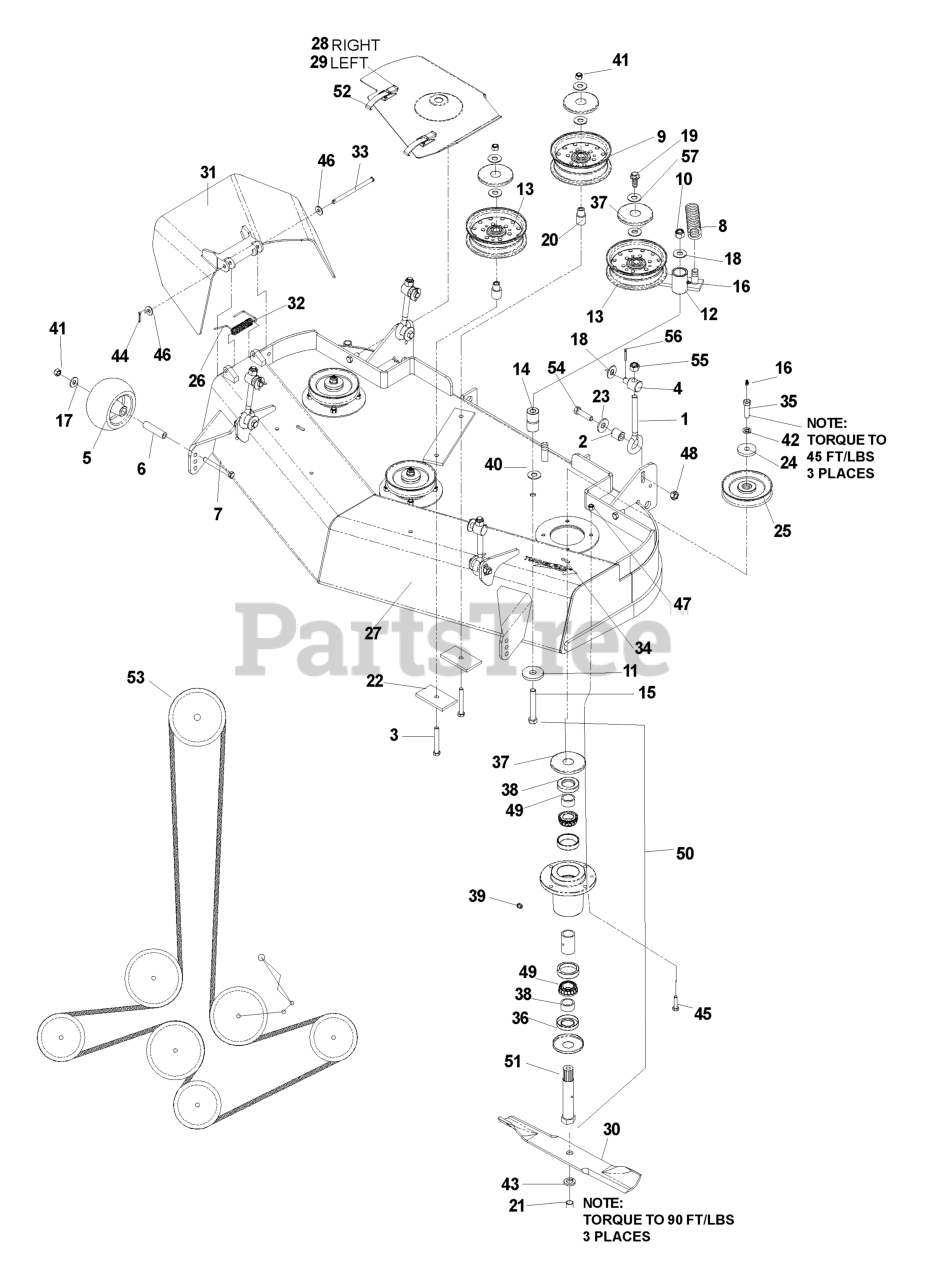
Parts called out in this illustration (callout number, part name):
3	HCS, 3/8-16 X 2 3/4, GR5
5	ROLLER, ANTI SCALP
7	HCS, 3/8-16 X 3 1/2, GR8
8	SPRING, EXTENSION
9	PULLEY, IDLER
10	NUT, 1/2-13, NYLOC
11	WASHER, .65
13	PULLEY, IDLER
14	BUSHING, PIVOT
15	HCS, 1/2-13 X 3 1/4, GR5
16	ZERK, STRAIGHT, 1/4-28
17	WASHER, 3/8
18	WASHER, 9/16
19	HCS, 3/8-16 X 1,GR5
20	BUSHING, IDLER
21	HCS, 5/8-18 X 1 1/4, GR5
22	PAD
23	SPRING WASHER, 1/2
24	WASHER, .469
25	PULLEY
26	CAP-SLEEVE
27	DECK W/DECALS
28	BELT SHIELD, RIGHT
29	BELT SHIELD, LEFT
30	BLADE, 14 5/8"
31	DISCHARGE CHUTE
32	SPRING, TORSION
33	PIN-CLEVIS, 5/16 DIA. X 5.19
34	DECAL, TUNNELRAM
35	HCS, 7/16-20 X 1 1/2, GR8, SPEC
36	BOTTOM DUST CAP
37	TOP DUST CAP
38	SHAFT SEAL
39	PLUG, VENTED
40	WASHER, 1/2
41	NUT, 3/8-16, NYLOC
42	LOCKWASHER, 7/16
43	LOCKWASHER, 5/8
44	PIN COTTER, 1/8 X 3/4
45	HCS, 5/16-18 X 1 1/4, GR5
46	WASHER, 5/16
47	NUT, 5/16-18, NYLOC
48	NUT, 7/16-14, CENTERLOCK, GR A
49	TOP & BOTTOM SPACER
50	SPINDLE ASSEMBLY
51	SPINDLE
52	DRAW LATCH
53	DECK BELT
54	HCS, 7/16-14 X 1 3/4, GR5
55	NUT, 1/2-13, NYLOC
56	PIN, COTTER, 1/8 X 1
57	WASHER, 3/8, SPEC
